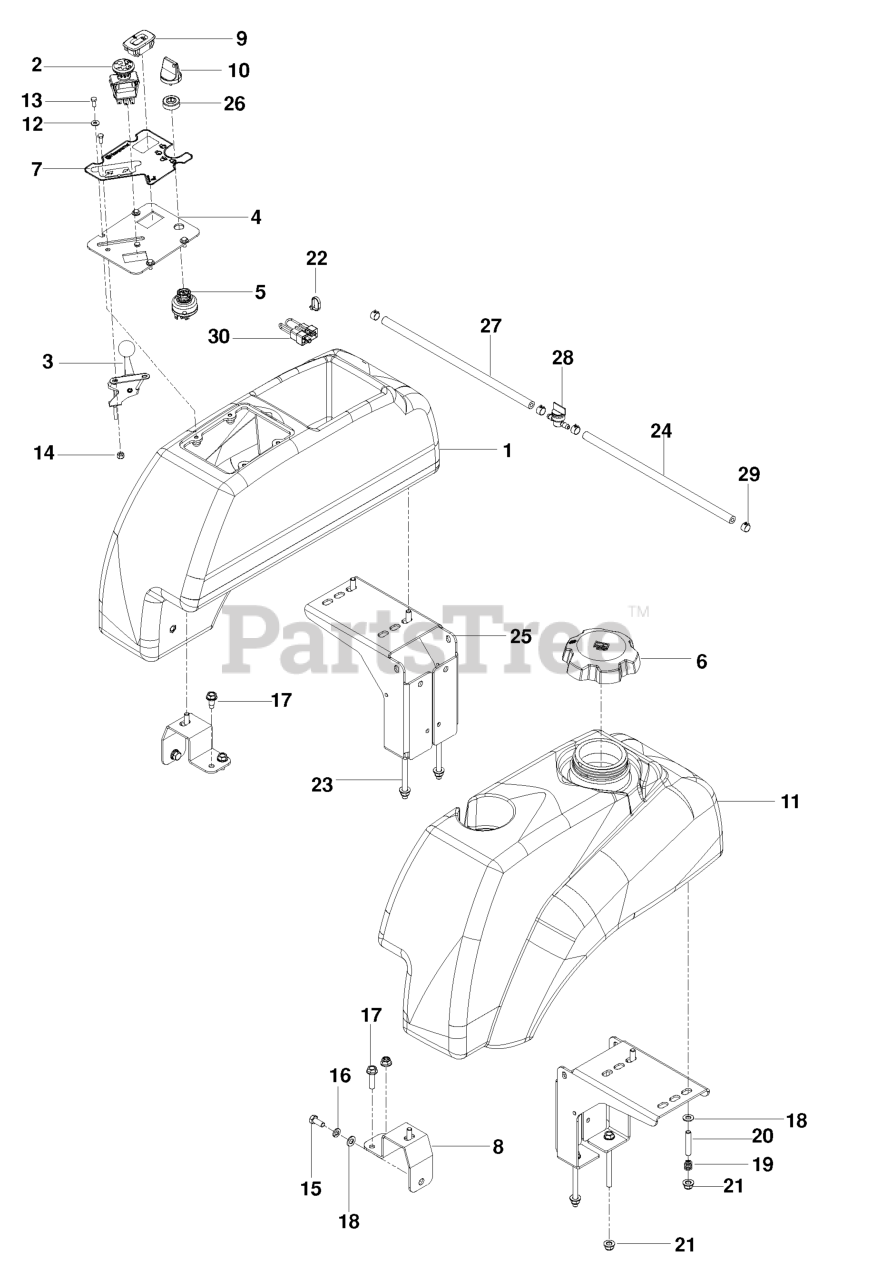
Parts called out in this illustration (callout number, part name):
1	FENDER CONSOLE
2	SWITCH, PTO 10 AMP
3	THROTTLE CABLE
4	RP.PLATE, CONSOLE, BLK
5	SWITCH, IGNITION, INDAK
6	FUEL CAP, HTC
7	DECAL, CONSOLE
8	SUPPORT, TANK, BLK
9	HOUR METER
10	KEY, IGNITION
11	LEFT TANK W/CUP HOLDER
12	WASHER #10
13	HCS #10-24 X 1/2
14	NUT 10-24 NYLOC
15	HCS 5/16C X 3/4
16	WASHER.LOCK.HVY.HLCL.SPR.5/16
17	RP BLT 5/16-18 X 1 THRD FORM D
18	FLAT WASHER 5/16 SAE
20	STUD, 5/16C
21	5/16-18 NYLOC FLANGE NUT
22	TIE, PLASTIC
23	HHFS 5/16-18 X 3 3/4
24	FUEL LINE 18"
25	MOUNT, TANK, ZT BLK
26	CAP IGNITION NUT
27	FUEL LINE 13"
28	FUEL VALVE
29	HOSE CLAMP
30	PLUG, TIMER
